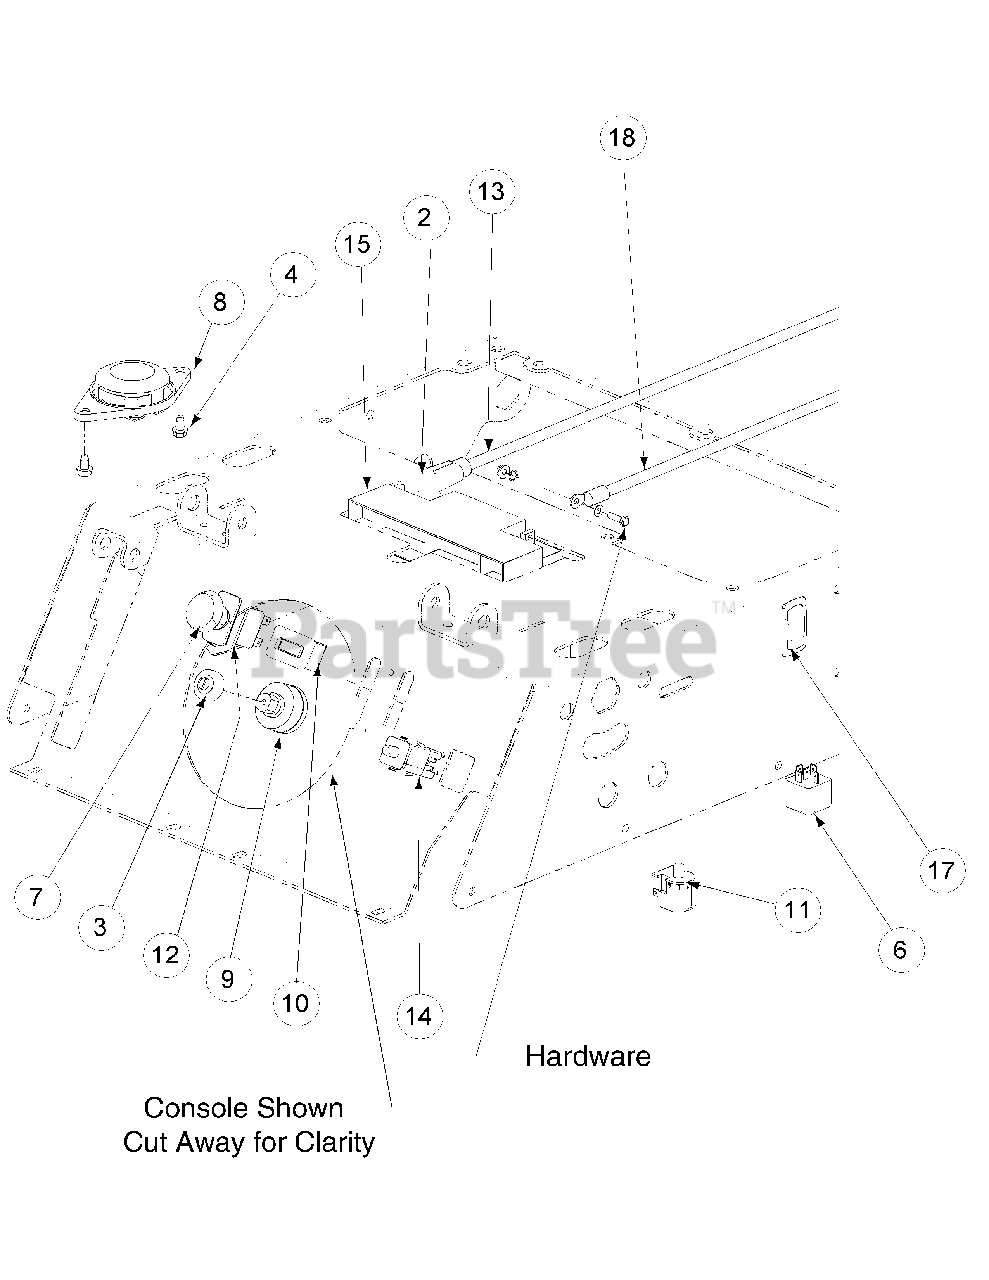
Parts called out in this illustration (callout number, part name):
1	Cable Tie, 3/16 x .05 x 7.4
2	Boot, 1" OD Rubber Battery-PST, Red
3	Nut, W/Cap, 5/8-32 Ignition
4	Screw, TT, 1/4-20, 0.5, Hex Index Washer
6	Relay 12V 40A
7	Switch, Electric, PTO
8	Normally Closed Seat Switch
9	Switch, Ignition, 6 Pin
10	Meter, Hour
11	Snap Mounting Switch, NO
12	PTO Switch Bracket
13	Cable, Battery, Red, 31"
14	Switch, Safety N.O./N.C.
15	Battery, Small 12CE18
18	Cable, Battery, Black, 31"
